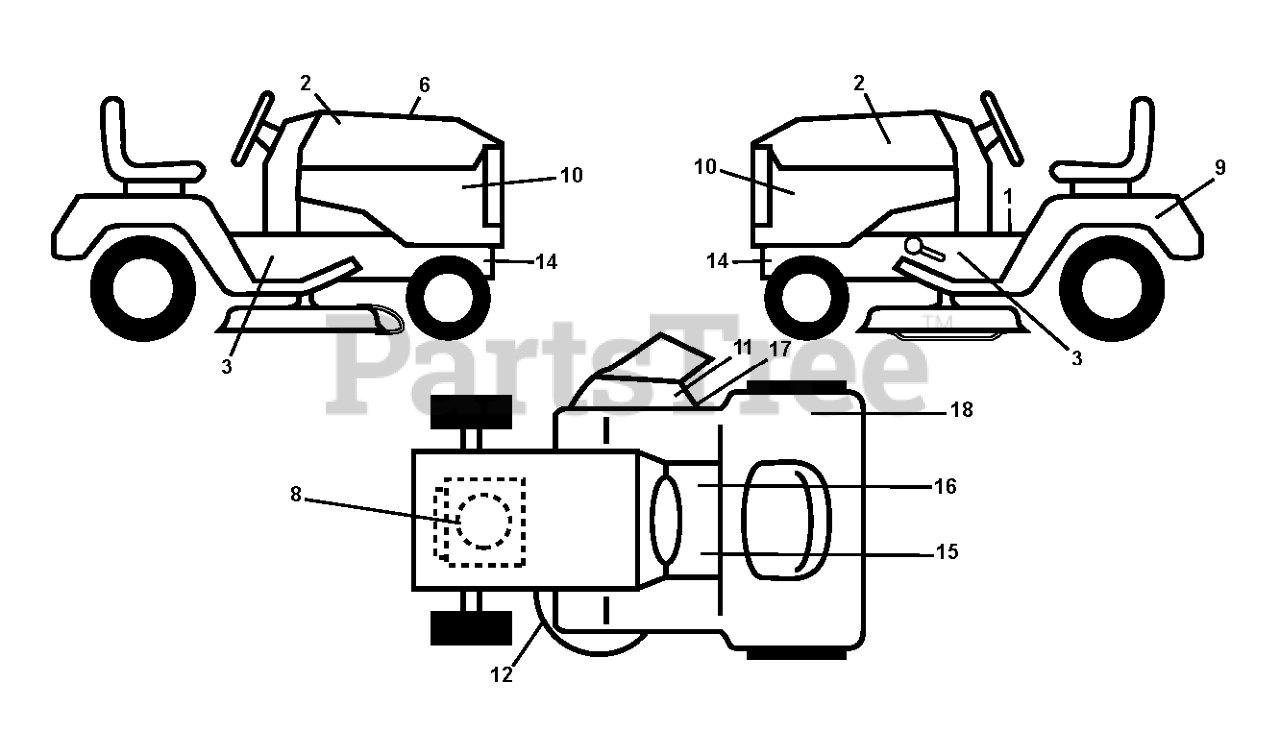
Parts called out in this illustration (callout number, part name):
1	LABEL
2	DECAL.HOOD.LOGO.ORANGE.HUSQVAR
8	DECAL
9	DECAL BTRY SYMBOLS
10	DECAL SIDE PANEL
11	DECAL.INTERNATIONL.CUTFINGER
12	DECAL.V-BELT.SCHEMATIC.36/38/9
15	DECAL
16	DECAL PARK BRAKE
17	DECAL, DEFLECT WARNING
18	Decal, Fender 100 DB/CE
